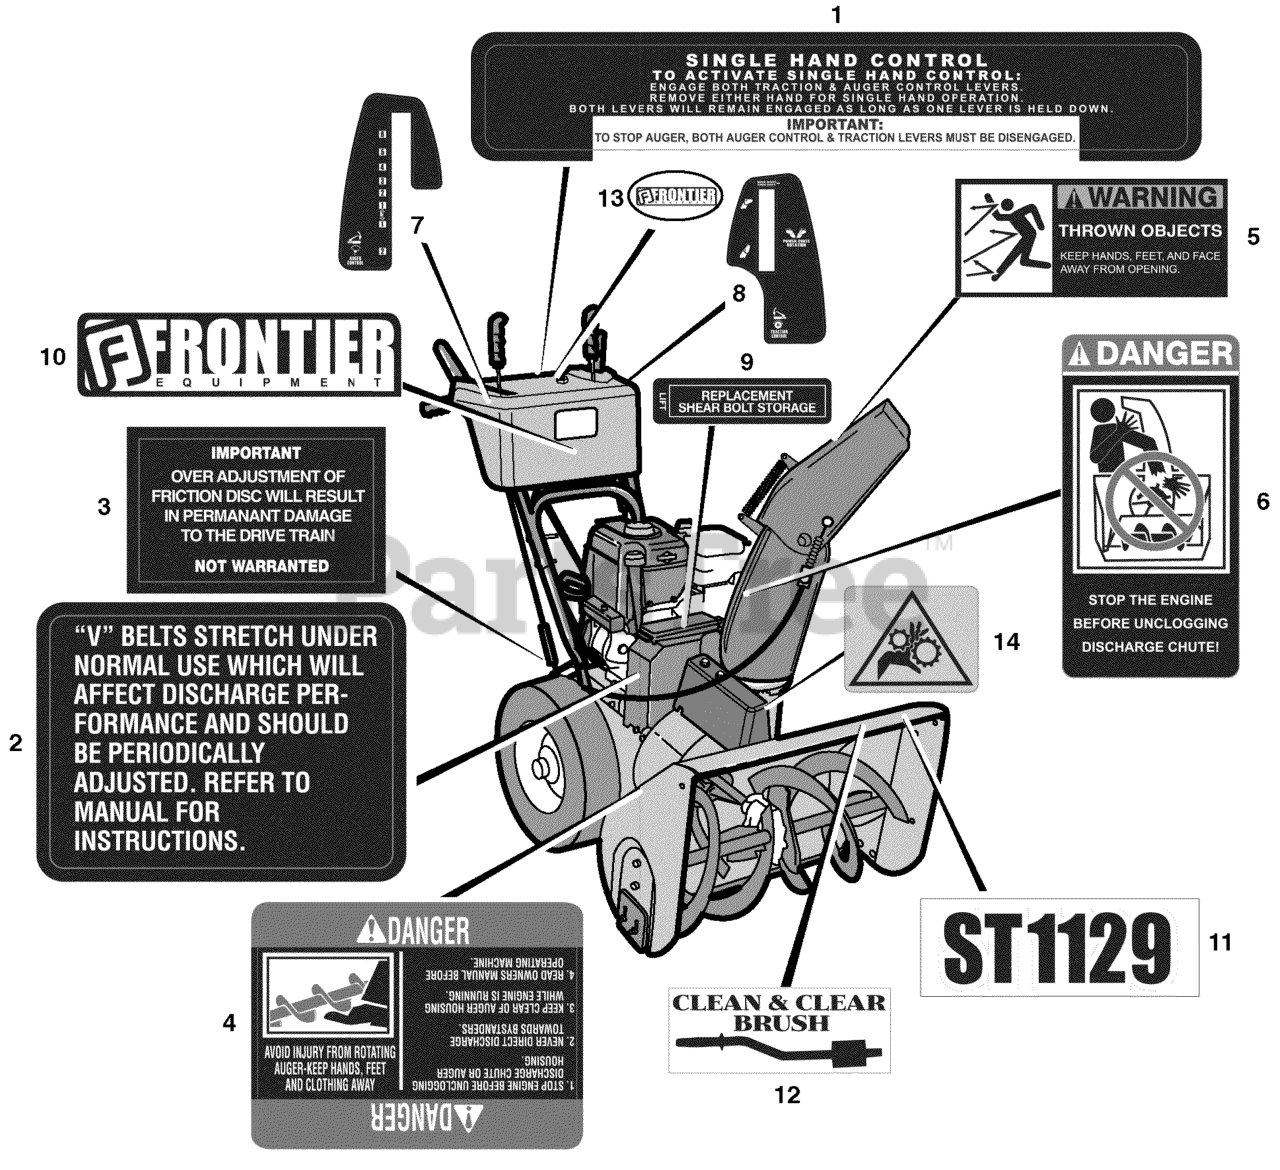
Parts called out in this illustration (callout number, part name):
1	DECAL, SINGLE HAND CONTROL
2	DECAL, V-BELTS
3	DECAL, OVER ADJUSTMENT
4	DECAL, ROTATING AUGER
5	DECAL, THROWN OBJECT
6	DECAL, UNCLOGGING CHUTE
7	DECAL, SPEED CONTROL
8	DECAL, REMOTE CHUTE CONTROL
9	DECAL, SHEAR BOLTS
10	LOGO NAMEPLATE, FRONTIER
11	DECAL, ST1129
12	DECAL, CLEAN & CLEAR BRUSH
13	DECAL, FRONTIER CIRCLE
14	DECAL, PINCH POINT - ELECTRIC CHUTE
